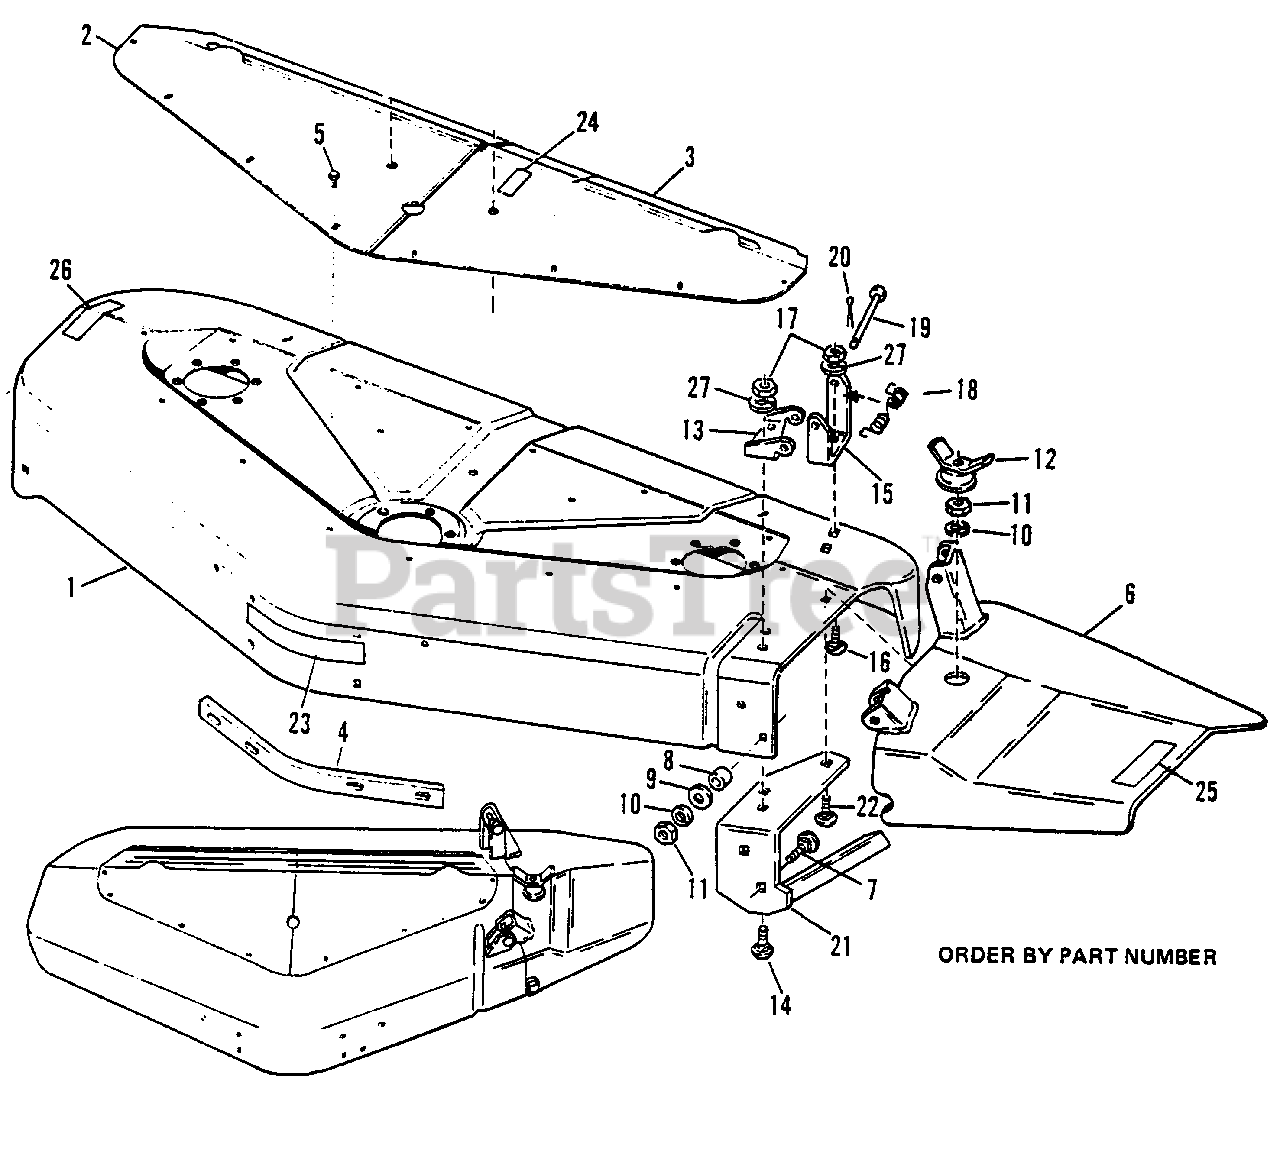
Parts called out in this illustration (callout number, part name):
1	Mower Housing
2	Cover R.H.
3	Cover, L.H.
4	Reinforcing bar
5	Self-Tapping Screw, 1/4"-20 x 3/8"
6	Deflector Assembly
7	Carnage Bolt, 3/8"-16 x 1-1/4"
9	Special Washer
10	Lockwasher, 3/8"
11	Full Hex Nut, 3/8"-16
12	Nut Assembly
13	Front Half Hinge
14	Carriage Bolt, 5/16"-18 x 1"
15	Rear Half Hinge
16	Carriage Bolt, 5/16" 18 x 3/4"
17	Full Hex Nut, 5/16" 18
20	Cotter Pin, 1/8" x 3/4"
21	Stone Guard Assembly
22	Carriage Bolt, 3/8"-16 x 1"
23	Film, Simplicity
24	Film Belt Installation
25	Decal, Danger
26	Decal, Caution
27	Lockwasher, 5/16"
